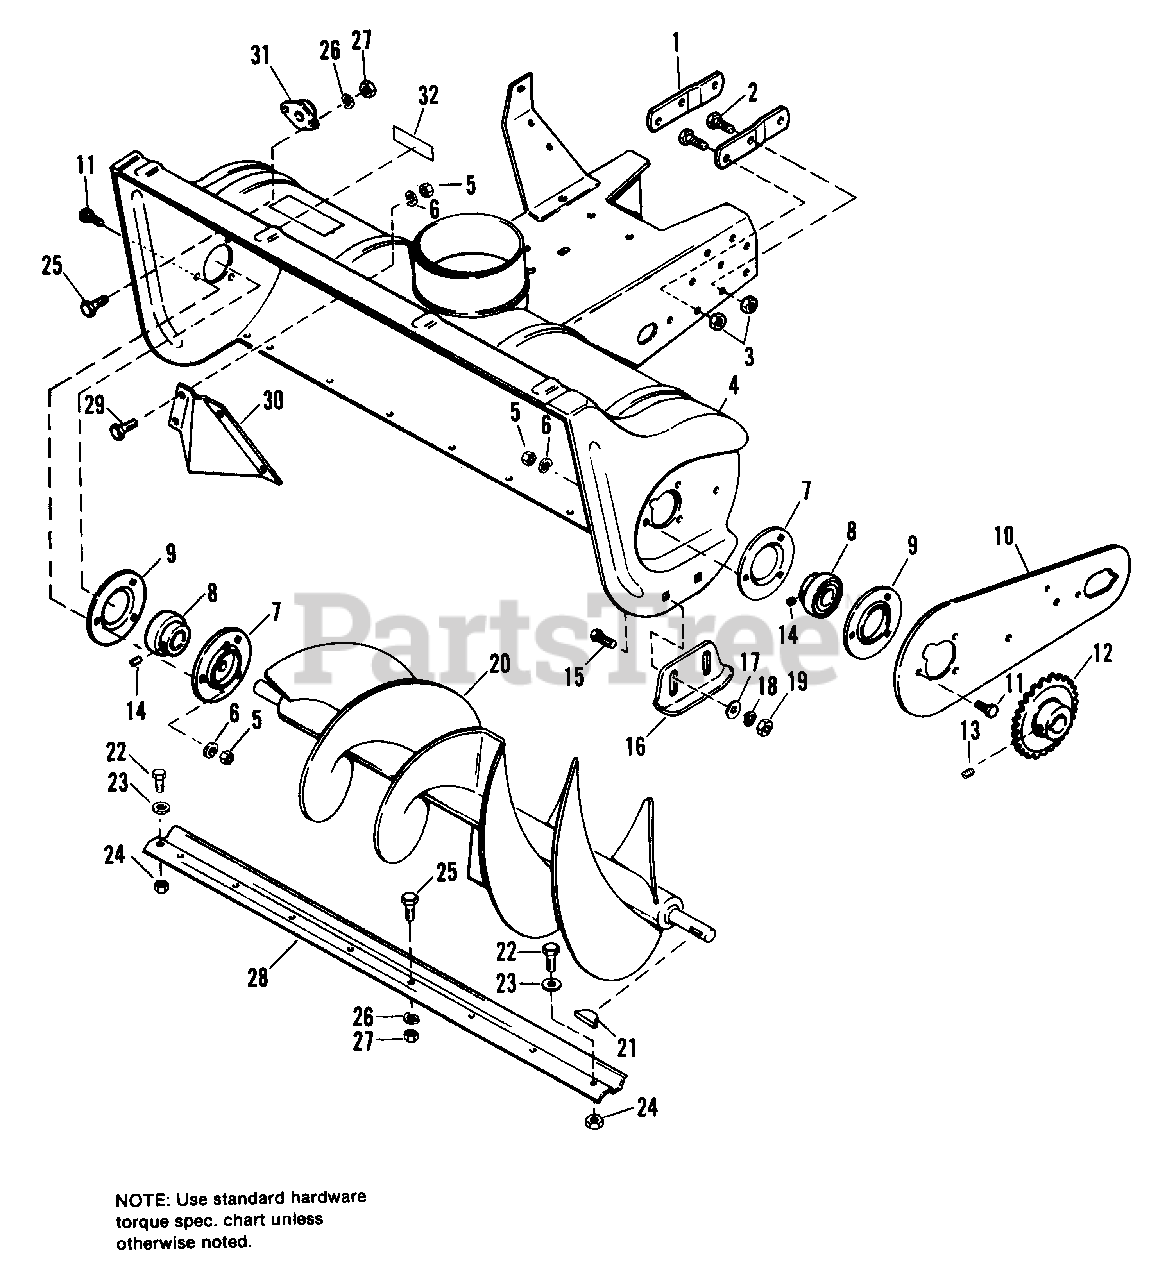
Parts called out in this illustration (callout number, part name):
1	CLIP, Frame
2	CAPSCREW, Hex Hd., 7/16-14 x 1
3	LOCKNUT Flange, 2-Way, 7/16-14
4	BODY & FRAME ASSY. (1690403 Only) 36"
4	BODY & FRAME ASSY. (1690513 Only) 42"
5	NUT, Hex, 5/16-18
6	LOCKWASHER, 5/16
7	FLANGE, Bearing, w/Fitting
8	BEARING, Cartridge
9	FLANGE, Bearing
10	PLATE, Side
11	CAPSCREW, Hex Hd., 5/16-18 x 3/4
13	SETSCREW, Skt. Hd., 5/16-18 x 5/16
14	SETSCREW, 1/4-28 x 1/4
15	BOLT, Carriage, 3/8-16 x 3/4
17	WASHER, Plain, 3/8
18	LOCKWASHER, 3/8
19	NUT, 3/8-16
20	ROTOR ASSY. (36" Only)
20	ROTOR ASSY. (42" Only)
21	KEY, Hi-Pro
22	CAPSCREW, Hex Hd., 5/16-18 x 5/8
23	WASHER, Plain, 1/4
24	LOCKNUT, 5/16-18
25	CAPSCREW, Hex Hd., 1/4-20 x 5/8 (Qty. 9 on 1690403 Only)
26	LOCKWASHER, 1/4 (Qty. 9 on 1690403 Only)
27	NUT, Hex, 1/4-20 (Qty. 9 on 1690403 Only)
28	SCRAPER, Body (1690403 Only) 36"
28	SCRAPER, Body (1690513 Only) 42"
29	CAPSCREW, Hex, 5/16-18 x 5/8
32	DECAL, Safety
